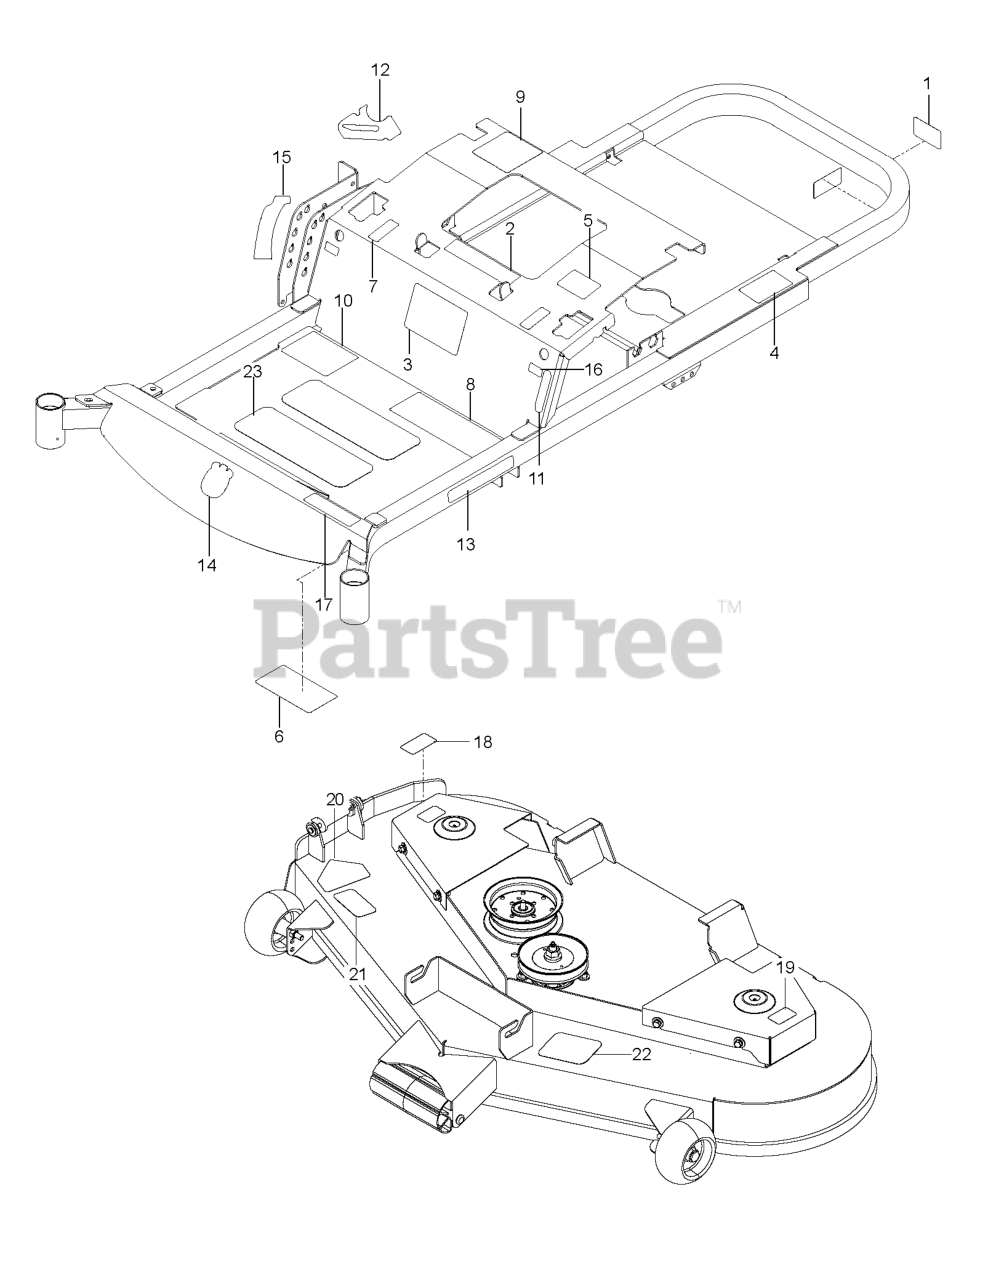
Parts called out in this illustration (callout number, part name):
1	DECAL, PROP. 65
2	EURO DECAL-BATTERY WARNIN6
3	DECAL, START
4	DECAL, DO NOT TOW
5	DECAL, EXITING MOWER
6	DECAL, SERVICE
7	DECAL, MOTION CONTROL
8	DECAL, SAFETY WARNING
9	DECAL, CUSTOMER RESPNSIBILITY
10	DECAL, WARNING
11	DECAL, PARK BRAKE
12	DECAL, IGNITION CONSOLE
13	DECAL.HOOD.LOGO.ORANGE.HUSQVAR
14	DECAL, CROWN H 70MM
15	DECAL, HEIGHT
16	DECAL, F.S.T.
17	DECAL, RZ4219
18	DECAL, CAUTION
19	DECAL, NO STEP
20	DECAL, CPSC
21	DECAL, EURO SEVERING
22	DECAL, BELT ROUTING
23	ANTI-SKID PAD
